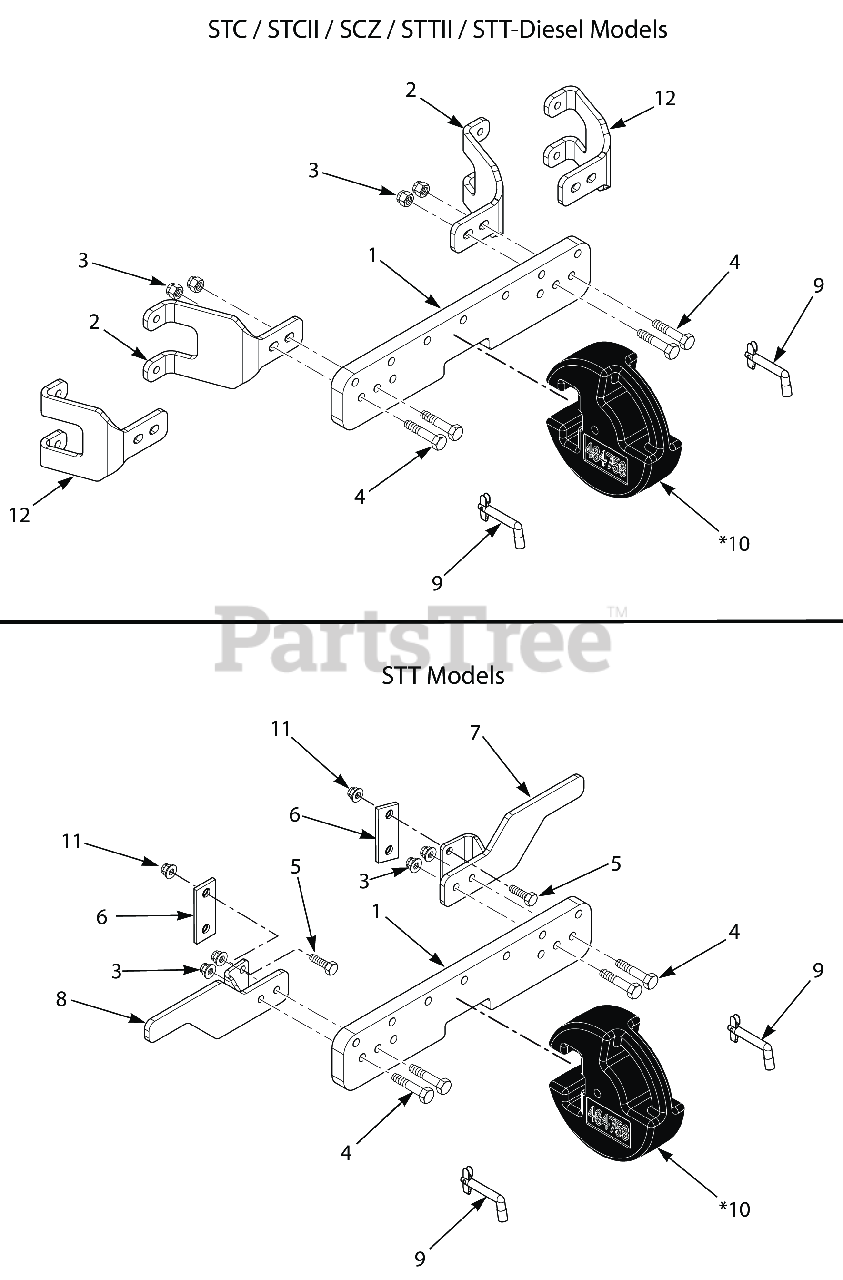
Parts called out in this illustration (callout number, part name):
1	Weight Bar
2	Bracket, LH Weight Bar (STC / STCII & SCZ48/52)
2	Bracket, RH Weight Bar (STC / STCII & SCZ48/52)
2	Bracket, Weight Bar (LH & RH for STT-Diesel, STTII52/61 & SCZ61)
3	Nut, Elastic Stop 1/2-13, (STT-52 & STTII-52)
4	HEX HD. BOLT 1/2-20 X 2 SPECIAL
5	Bolt, Hex Head, 3/8-16 x 1-1/2"
6	Clamp, Bar
7	Mounting Bracket Weldment, LH Weight Bar
8	Mounting Bracket Weldment, RH Weight Bar
9	Pin, Weight Retention
10	Weight
11	Nut, Flange Elastic Stop Nut, 3/8-16
12	BRKT, WEIGHT BAR
